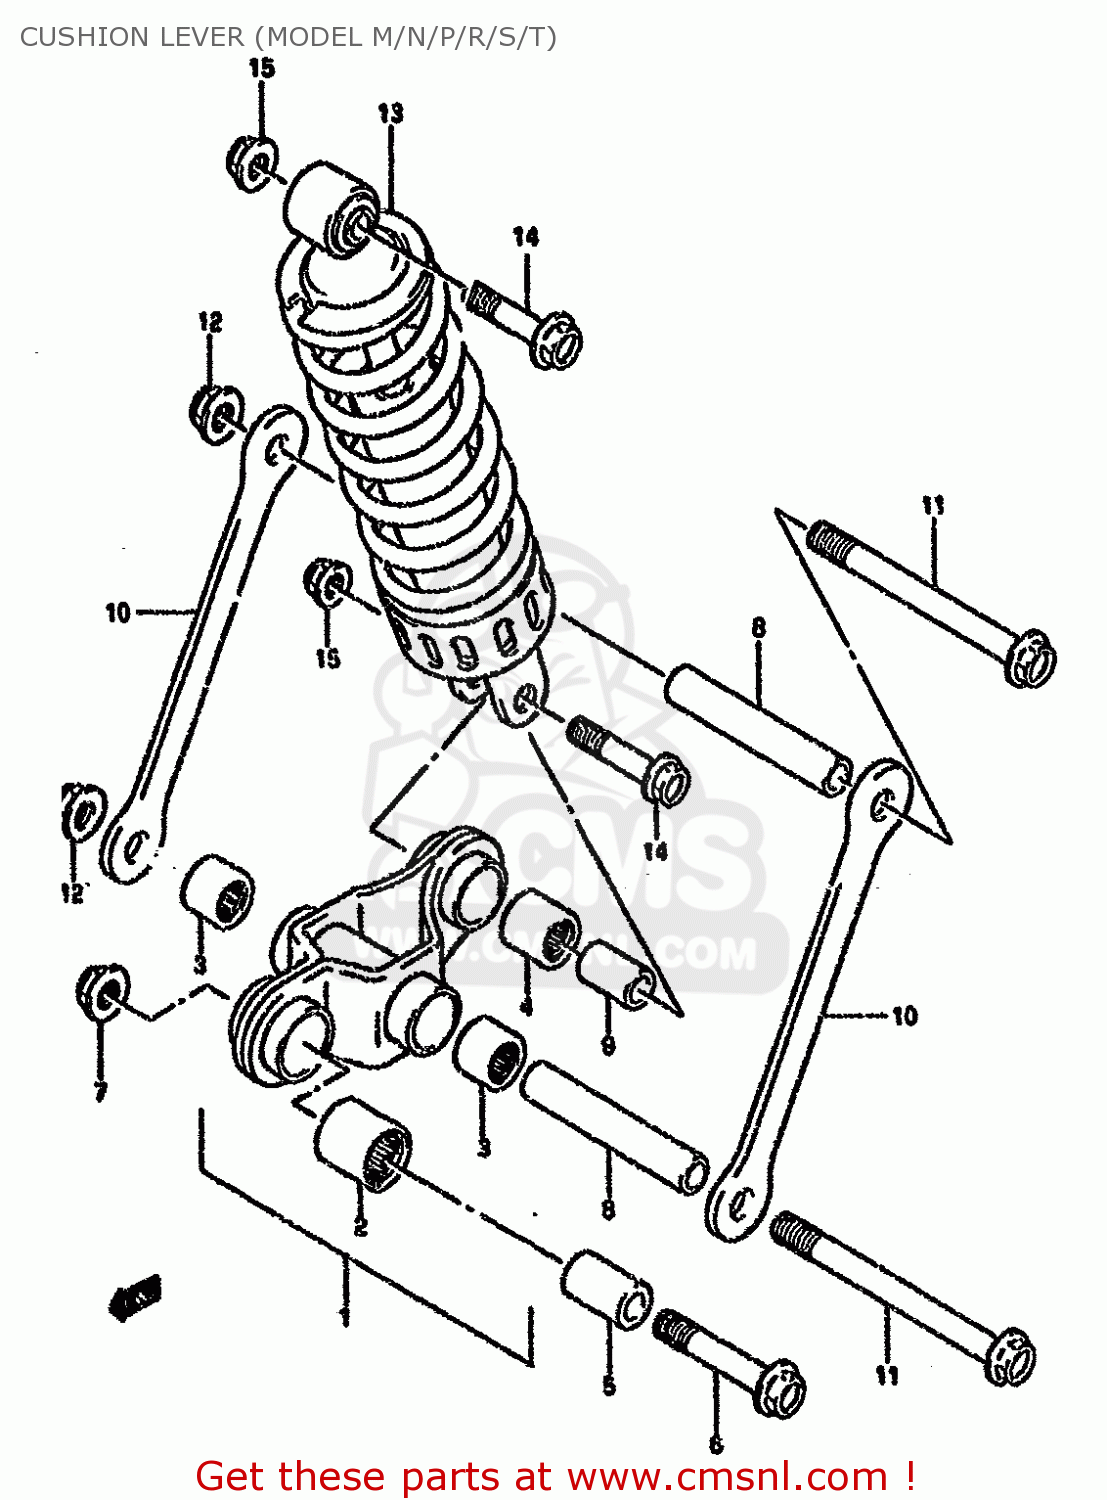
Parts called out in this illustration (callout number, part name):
1	LEVER SET,RR CUSHION
2	BEARING(20X27X26)
3	BEARING(17X24X25)
4	BEARING(17X24X26)
5	SPACER,REAR CUSHION LEVER
6	BOLT(12X57)
7	NUT 12MM
8	SPACER (12X17X89)
9	SPACER,RR CUSHION LEVER
10	ROD,RR CUSHION LEVER
11	BOLT(12X118)
12	NUT 12MM
13	ABSORBER ASSY,RR SHOCK
14	BOLT(10X52)
15	NUT
